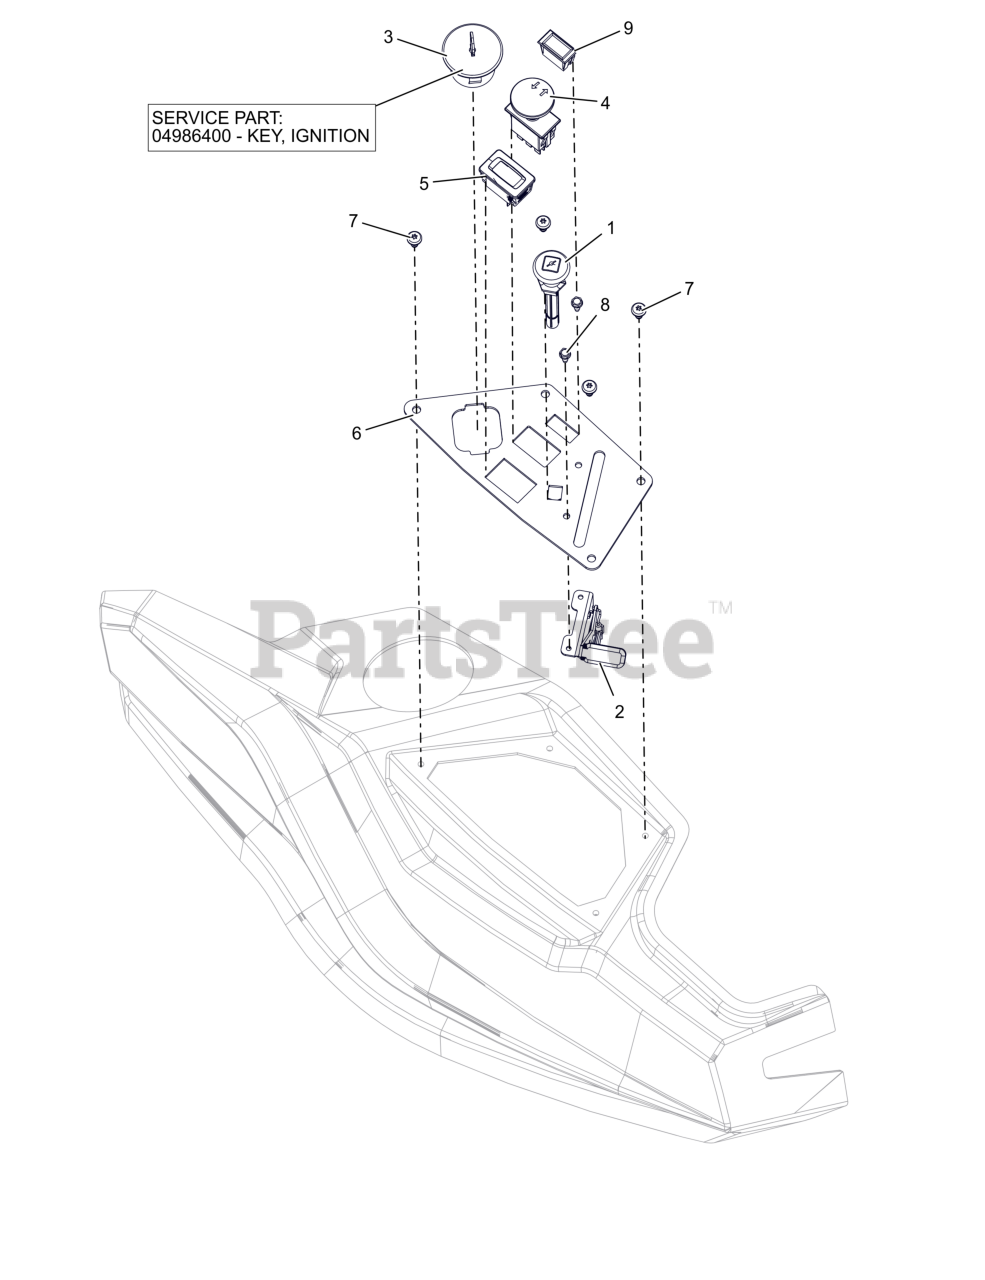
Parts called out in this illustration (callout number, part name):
1	CABLE, CHOKE (SNAP IN)
2	CABLE, THROTTLE
3	KEYSWITCH-IGNITION 3 POS
3	KEY, IGNITION
4	SWITCH, CLUTCH (YELLOW)
5	HOUR METER
6	PANEL, CONTROL (ORANGE)
7	SCR-PAN .25-15X.50 6L H/LZB500
8	SCR,TAP #10-24X.50 HWH TR ZCC
9	SWITCH,BLANK
